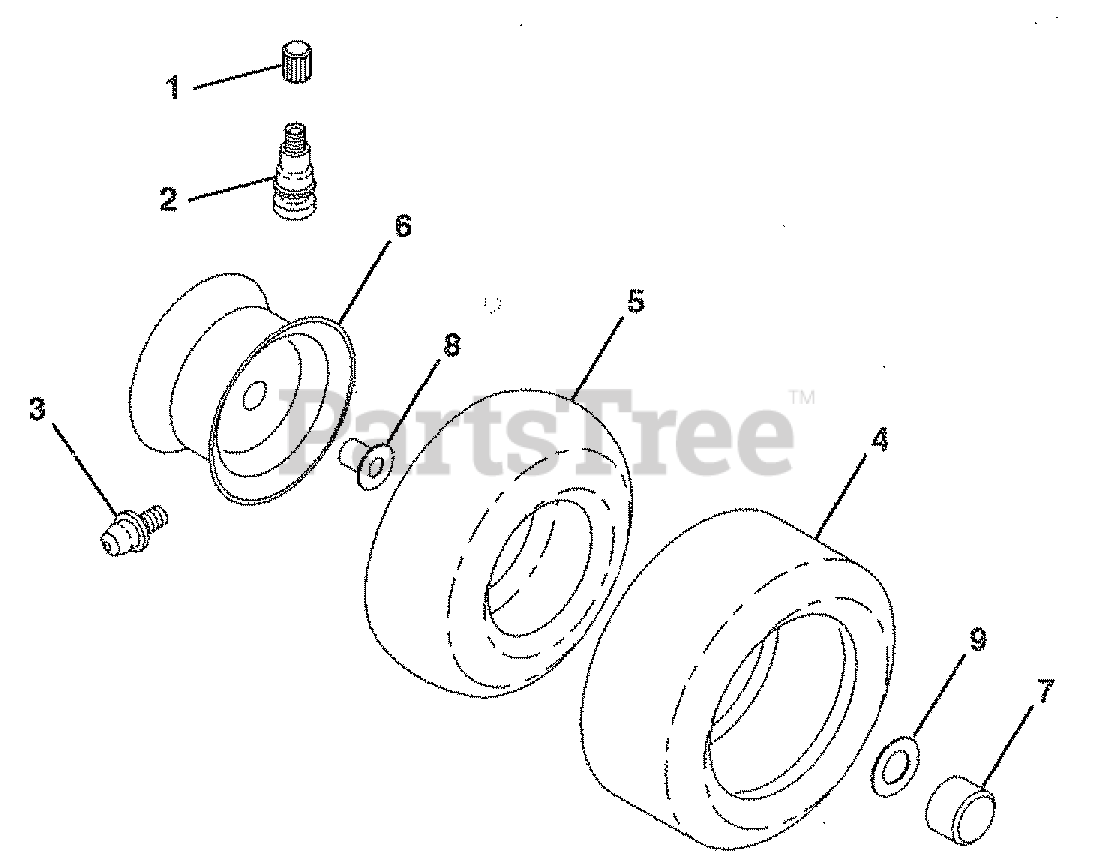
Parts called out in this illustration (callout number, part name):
1	Cap, Valve
2	Stem, Valve
3	Fitting, Grease
4	Tire, Front
5	Tube, Front
6	Rim, Front
8	Bearing, Flange
9	Washer 25/32 x 1-5/8x16Ga.
